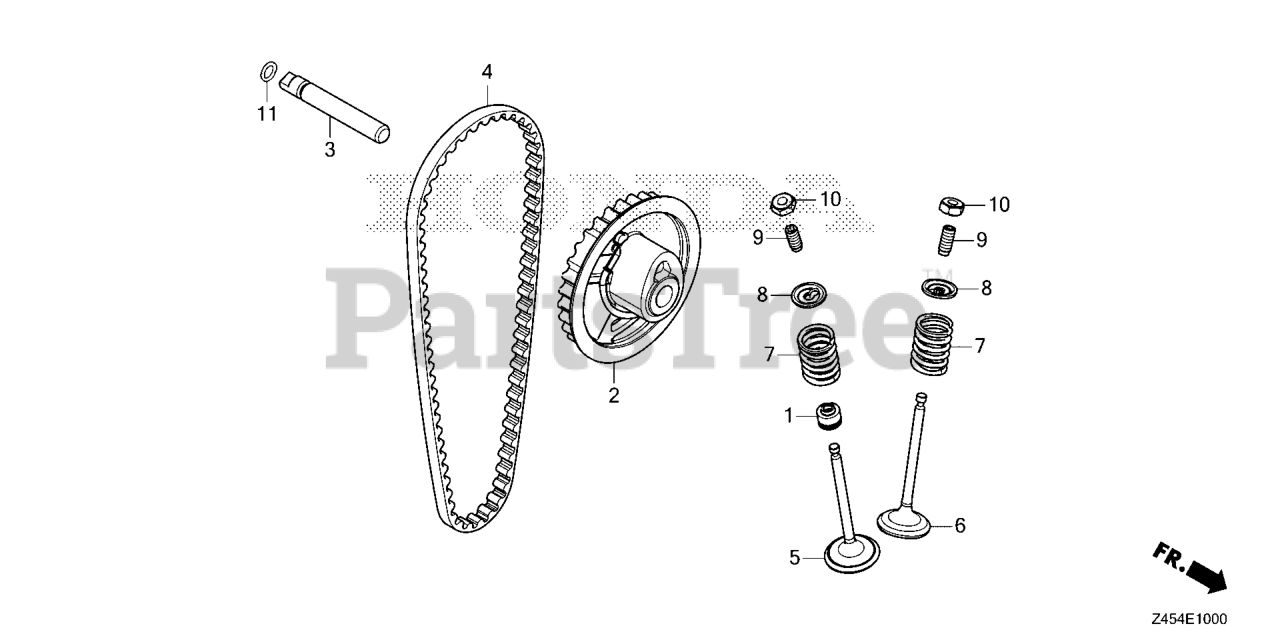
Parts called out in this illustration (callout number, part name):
1	SEAL, VALVE STEM
2	PULLEY COMP, CAM
3	SHAFT, CAM PULLEY
4	BELT (67YU7) (G-200)
5	VALVE, INLET
6	VALVE, EX.
7	SPRING, VALVE
8	RETAINER, VALVE SPRING
9	SCREW, TAPPET ADJ
10	NUT, TAPPET ADJ.
11	O-RING (6.8X1.9) (ARAI)
